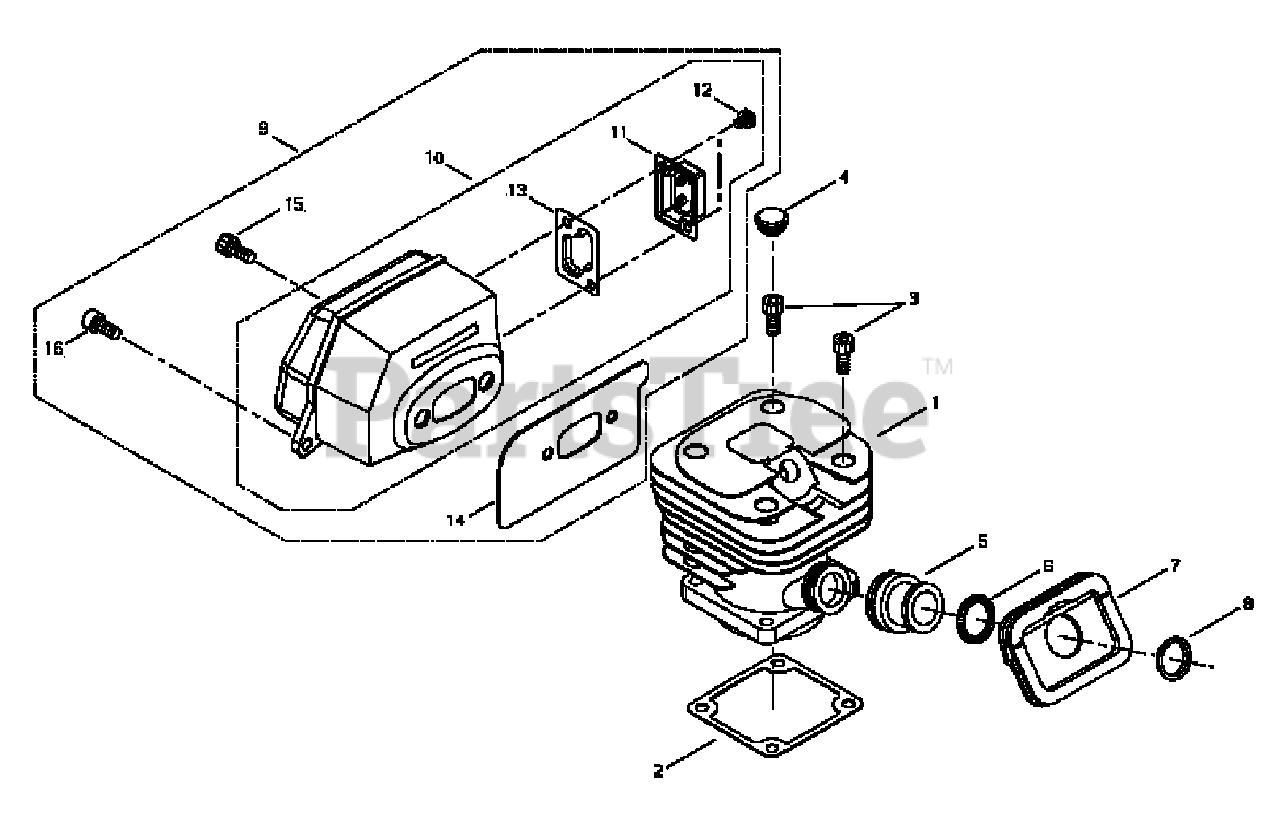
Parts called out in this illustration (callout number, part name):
1	CYLINDER
2	GASKET, CYLINDER
3	BOLT
4	PLUG
5	SEAL
6	SPRING
7	SEAL
8	SLEEVE
9	MUFFLER ASSY
10	MUFFLER SUB ASSY
11	GUIDE, EXHAUST
12	SCREW - 4X6
13	SCREEN, SPARK ARRESTOR
14	GASKET, EXHAUST
15	BOLT
16	BOLT
